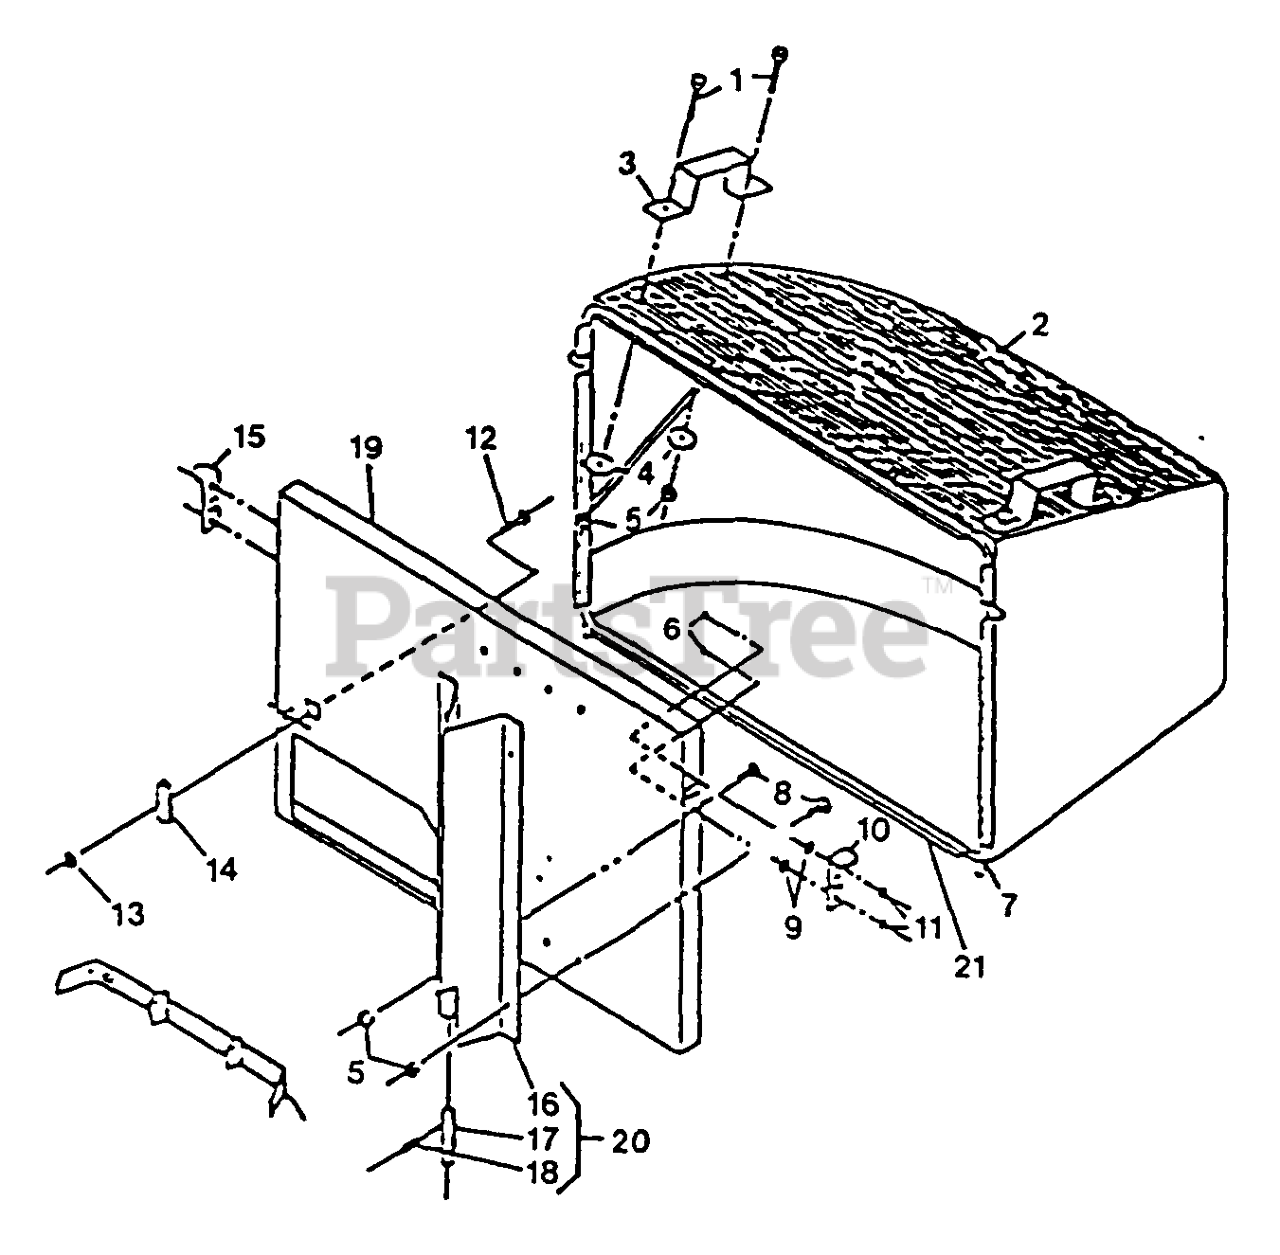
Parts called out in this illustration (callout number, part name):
7	FRAME-CATCHER
9	WASHER-SPRING
10	LATCH-CATCHER, RH
14	LATCH-CATCHER, GRASS
15	LATCH-CATCHER, LH
17	SHAFT-CATCHER, GRASS
18	PIN-ROLL
19	WLD,BACK PLATE
20	Rear Frame Assy
